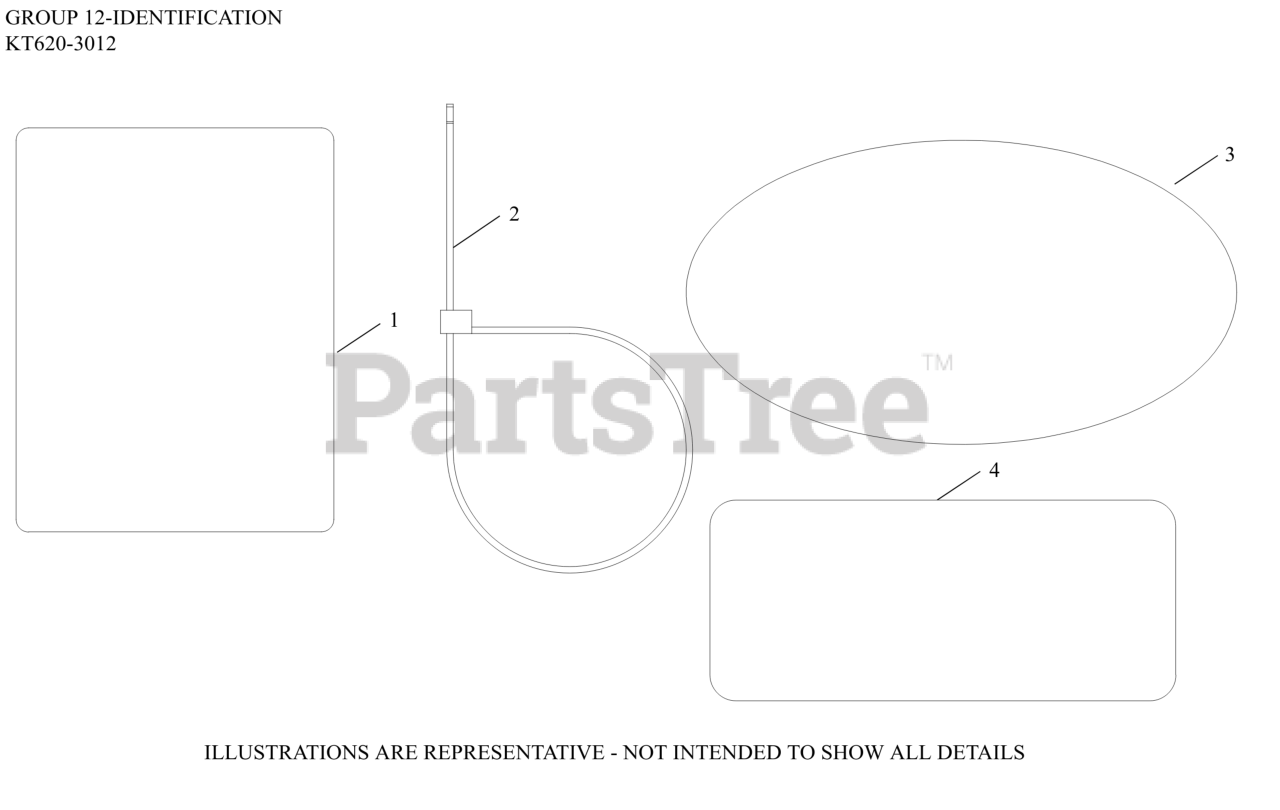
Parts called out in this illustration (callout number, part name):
1	LABEL, CLEAR LAMINATION
3	LABEL, 6600 SERIES (21HP)
3	LABEL, PRO PERFORMANCE FILTRATION SYSTEM
4	LABEL, CANADIAN COMPLIANCE
